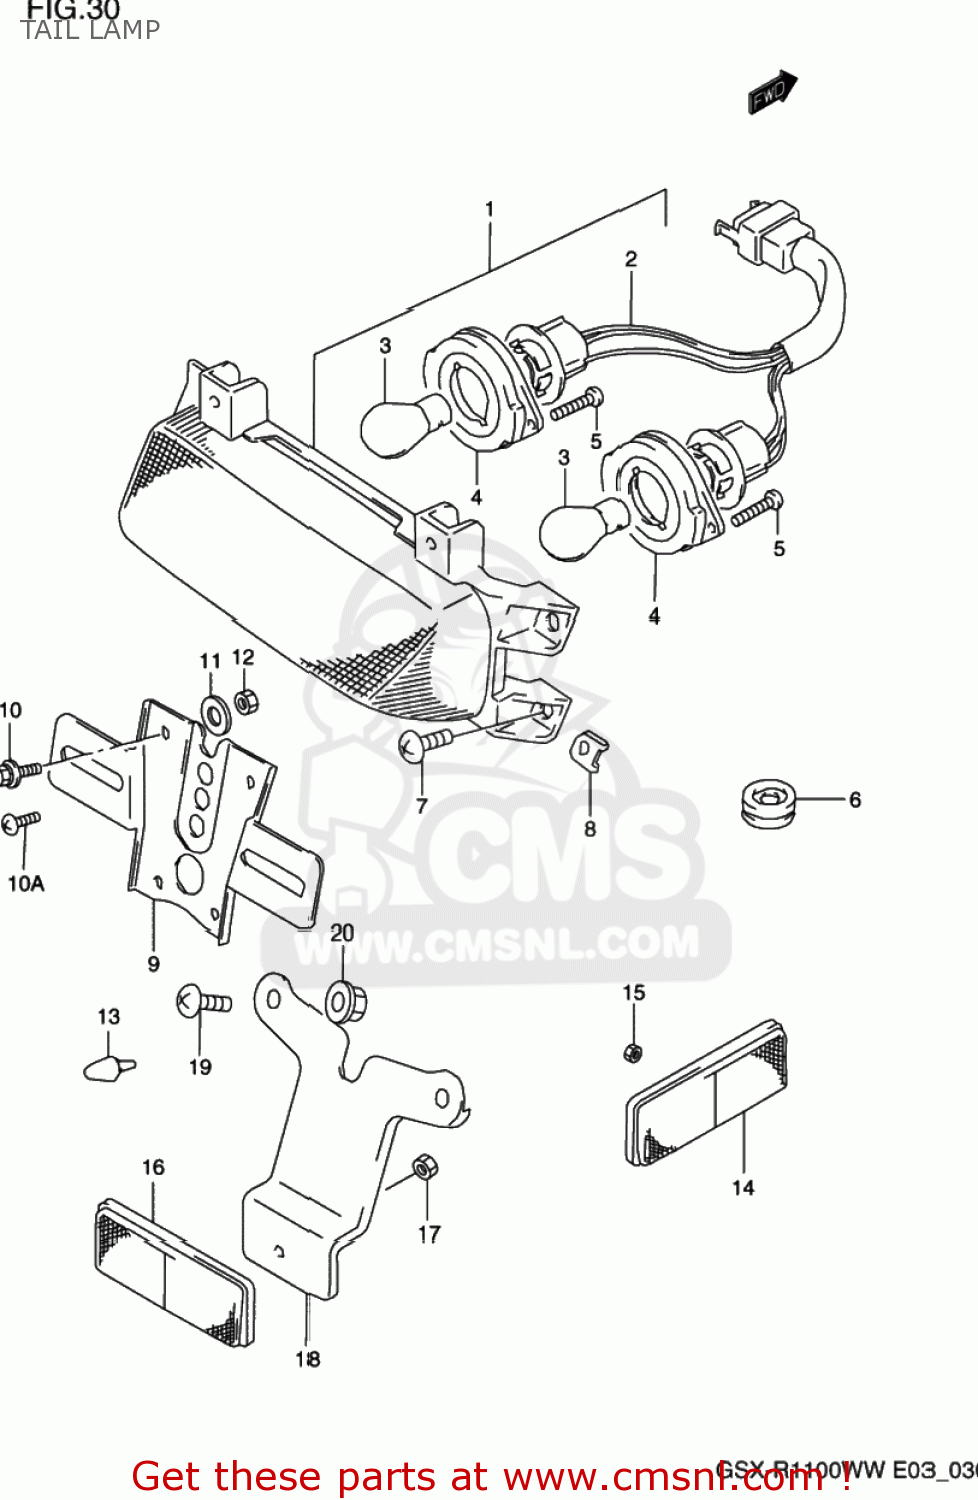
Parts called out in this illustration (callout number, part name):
1	LAMP ASSY,RR COMBINATION
2	SOCKET & CORD ASSY
3	BULB(12V21/5W,BF141-49642A)
4	CUSHION
5	SCREW
6	GROMMET
7	SCREW 5X12
8	NUT
9	BRACKET,LICENSE PLATE
10	BOLT
10A	SCREW 6X12
11	WASHER,COVER,FRONT
12	NUT
13	CUSHION
14	REFLECTOR ASSY,RR
15	NUT
16	REFLECTOR ASSY,RR
17	NUT
18	BRACKET,RR RR
19	SCREW 6X12
20	NUT
